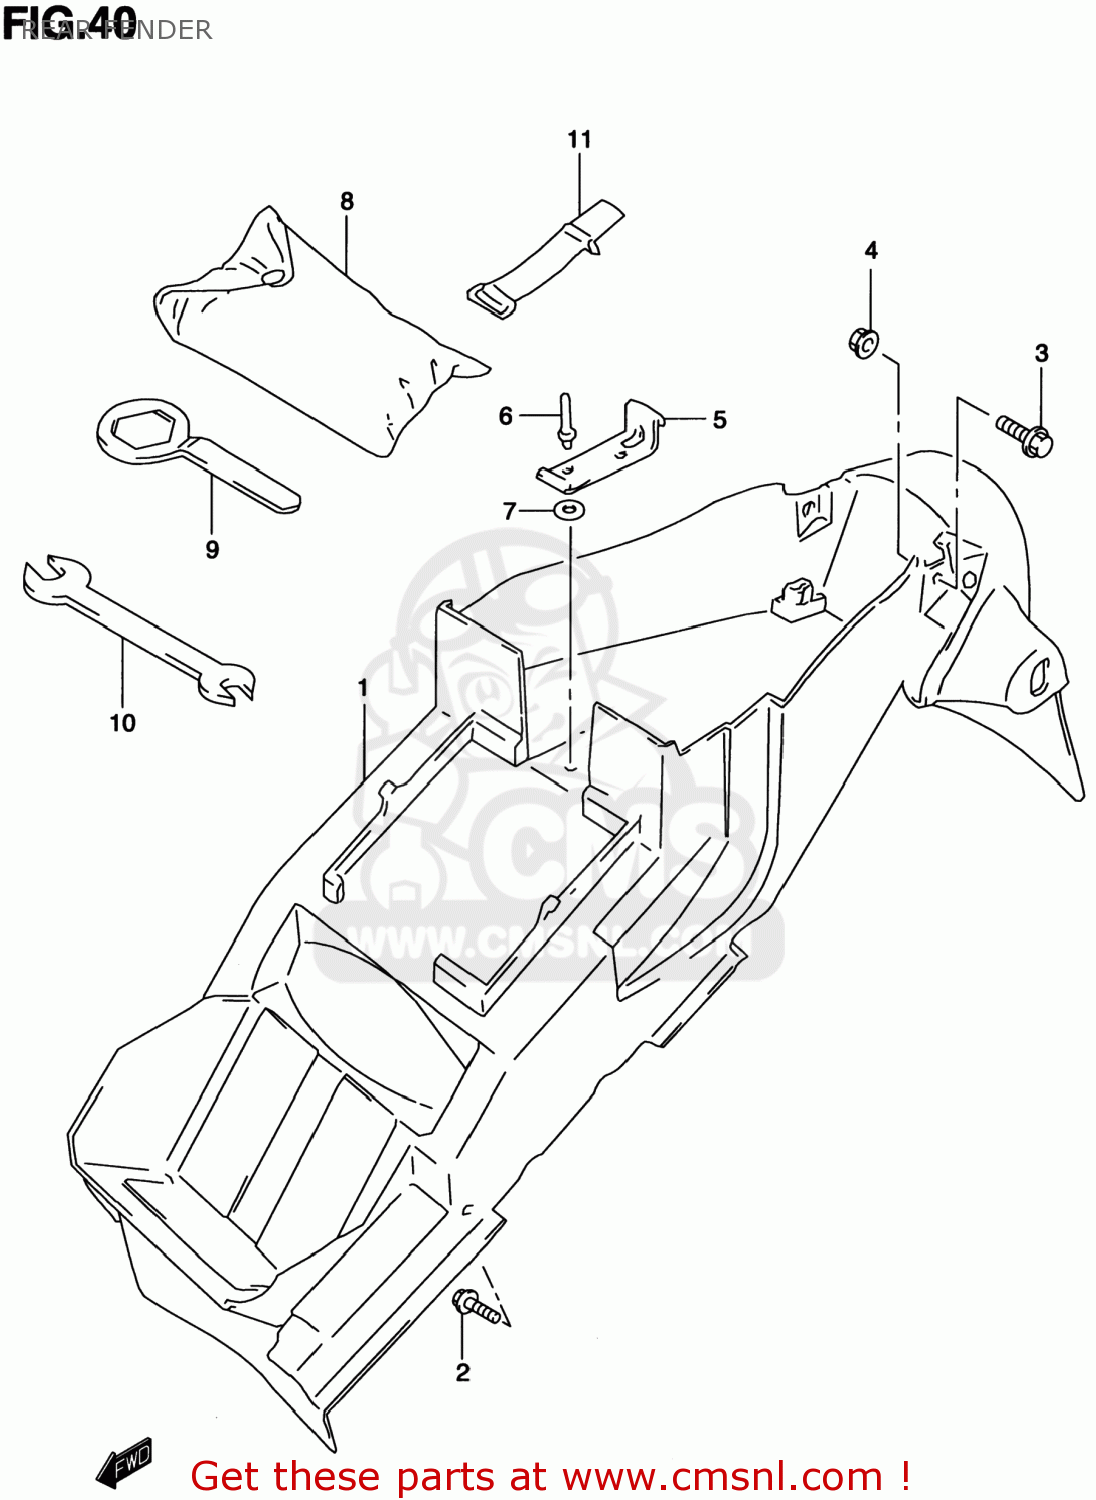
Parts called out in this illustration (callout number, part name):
1	FENDER,RR
2	BOLT 6X16.5
3	BOLT 6X16
4	NUT
5	HOLDER,TOOL
6	RIVET
7	WASHER
8	TOOL ASSY
9	RING SPANNER(36)
10	OPEN SPANNER(8X10)
11	BAND,TOOL
